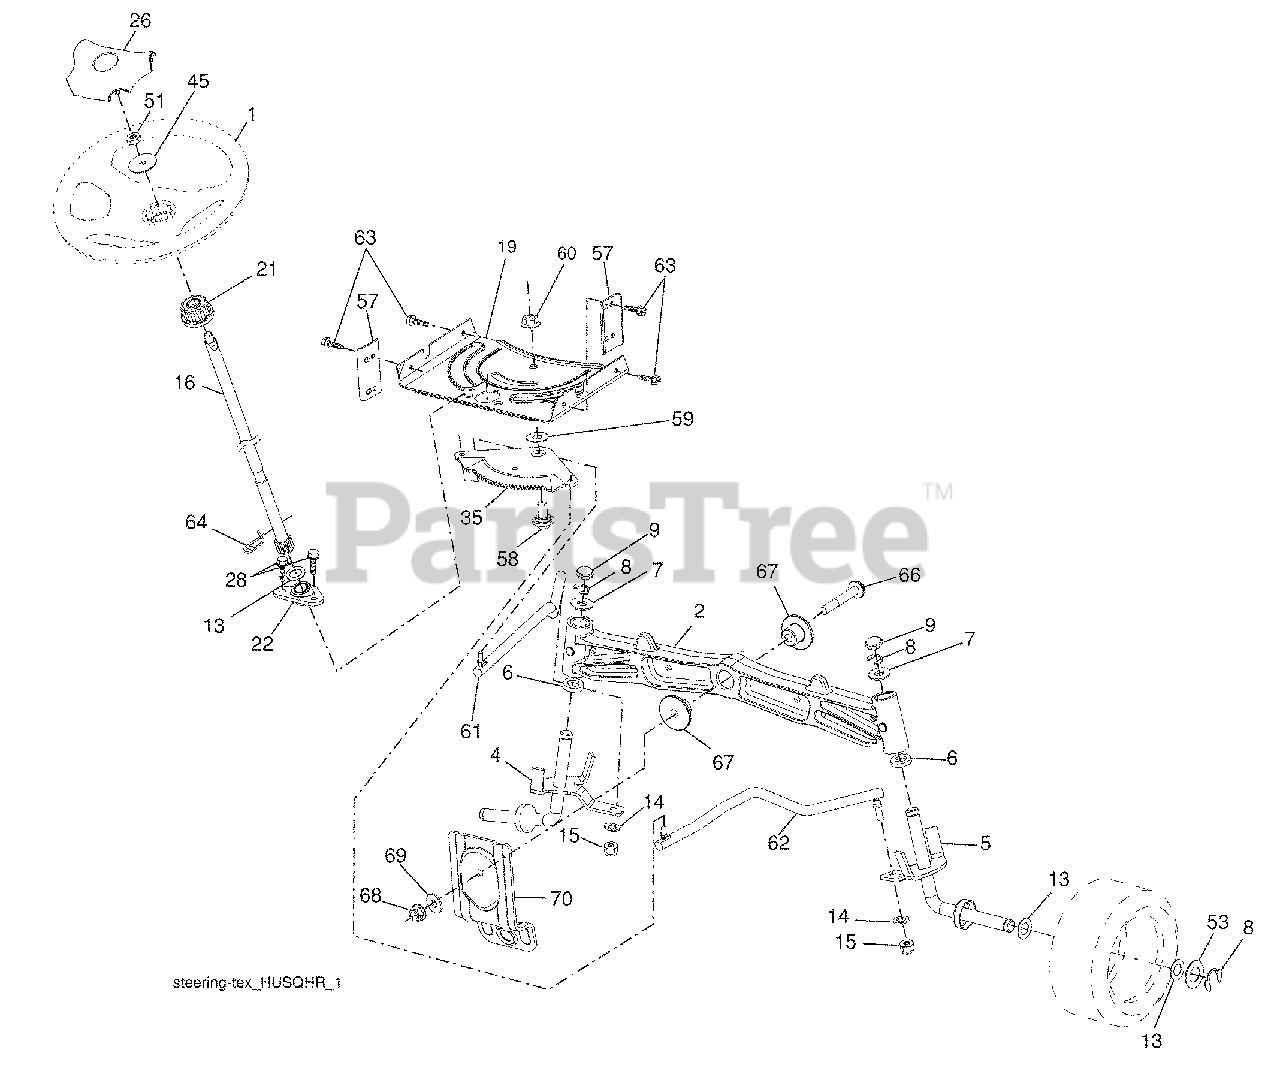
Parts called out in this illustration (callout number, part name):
1	Wheel, Steering
2	Axle Asm., Front
4	Spindle Asm., LH
5	Spindle Asm., RH
6	Washer Thrust .75 x 1.230
7	Washer 25/32 x 1-5/8 x 16 Ga.
8	Ring, Clip #T5304-75
9	Cap, Spindle
13	Washer 25/32 x 1-1/4 x 16 Ga.
14	Washer, Lock Hvy Hlcl Spr 3/8
15	Nut, Crown Lock 3/8-24 unf
16	Shaft Steering
19	Plate Steering
21	Adapter, Wheel Steering
22	Bushing, Strg. Blk
26	Insert, Wheel Steering
28	Screw 3/8-16 x 3/4
35	Gear, Sector Plate
45	Washer 9/16 ID x 2-3/8 OD 12 Ga.
51	Nut Hex Jam Toplock 1/2-20 unf
53	Washer Hardened .793 x 1.637 x .060
57	Bracket Upstop
58	Bolt Shoulder Sector Pivot CFM
59	Washer Thrust Sector Steering
60	Nut Flange Lock 5/8-11
61	Draglink LH
62	Draglink, RH
63	Screw 5/16-18 x 3/4
64	Retainer Clip Spring Steering
66	Bolt Hex Fghd 7/16-14 x 3 Serr
67	Bushing PM Front Axle
68	Nut Lock Flange 7/16-14 Gr. 5
69	Washer 1.5 x .505 x .118
70	Bracket Deck Susp. Front
